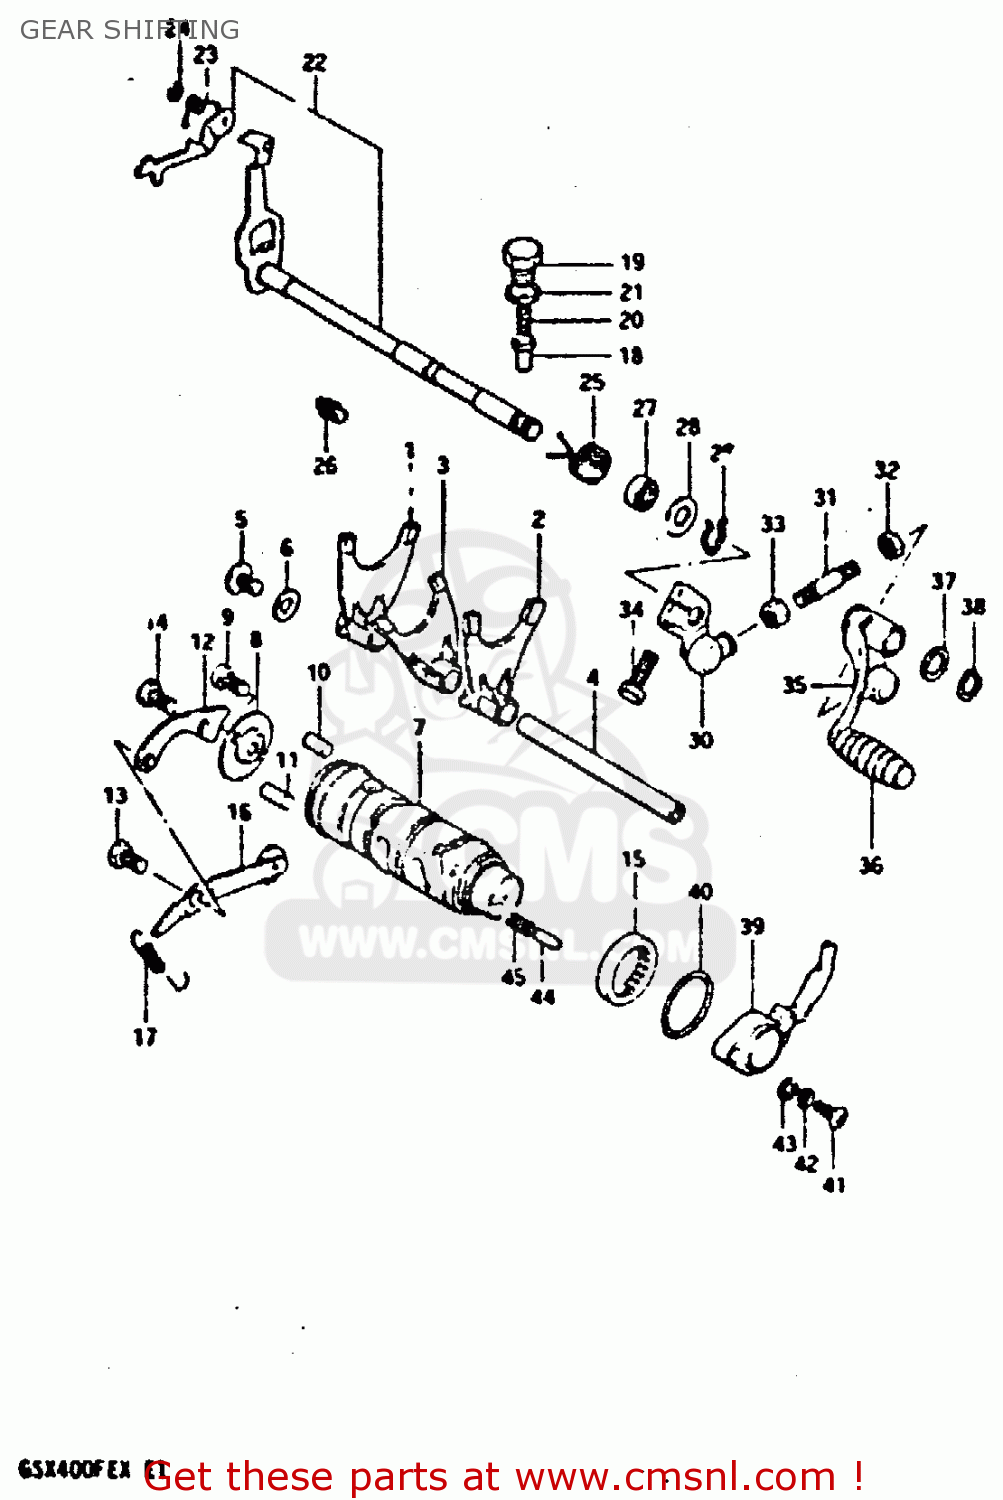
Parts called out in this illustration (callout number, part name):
1	FORK, GEAR SHIFTING
2	FORK, GEAR SHIFTING
3	FORK, GEAR SHIFTING
4	SHAFT,GEAR SHIFT FORK
5	SCREW
6	WASHER
7	CAM,GEAR SHIFT
8	RETAINER,GEAR SHIFT CAM DR PIN
9	SCREW
10	PIN
11	PIN(4X18.5)
12	GUIDE,GEAR SHIFTING CABLE
13	BOLT
14	BOLT, UPPER
15	BEARING(40X47X12)
16	STOPPER,GEAR SHIFT CAM NO.1
17	SPRING
18	STOPPER,GEAR SHIFT CAM NO.2
19	HOLDER,GEAR SHIFT CAM STOP SPR
20	SPRING
21	GASKET(14X19.2X2) (NAS)
22	SHAFT, GEAR SHIFTING
23	SPRING
24	E RING
25	SPRING
26	STOPPER,GEAR SHIFT CAM
27	OIL SEAL
28	WASHER (12.5X27X1.6)
29	SPRING,RETAINER
30	ARM,GEAR SHIFT LINK
31	ROD,GEAR SHIFT LINK
32	NUT
33	NUT
34	BOLT
35	LEVER ASSEMBLY,GEAR SHIFTING
36	RUBBER,GEAR SHIFT PEDAL
37	WASHER(12.5X20X1)
38	CIRCLIP
39	BASE ASSEMBLY,NEUTRAL SWITCH TERMINAL
40	O RING
41	SCREW 5X20
42	LOCK WASHER
43	WASHER
44	CONTACT
45	SPRING
